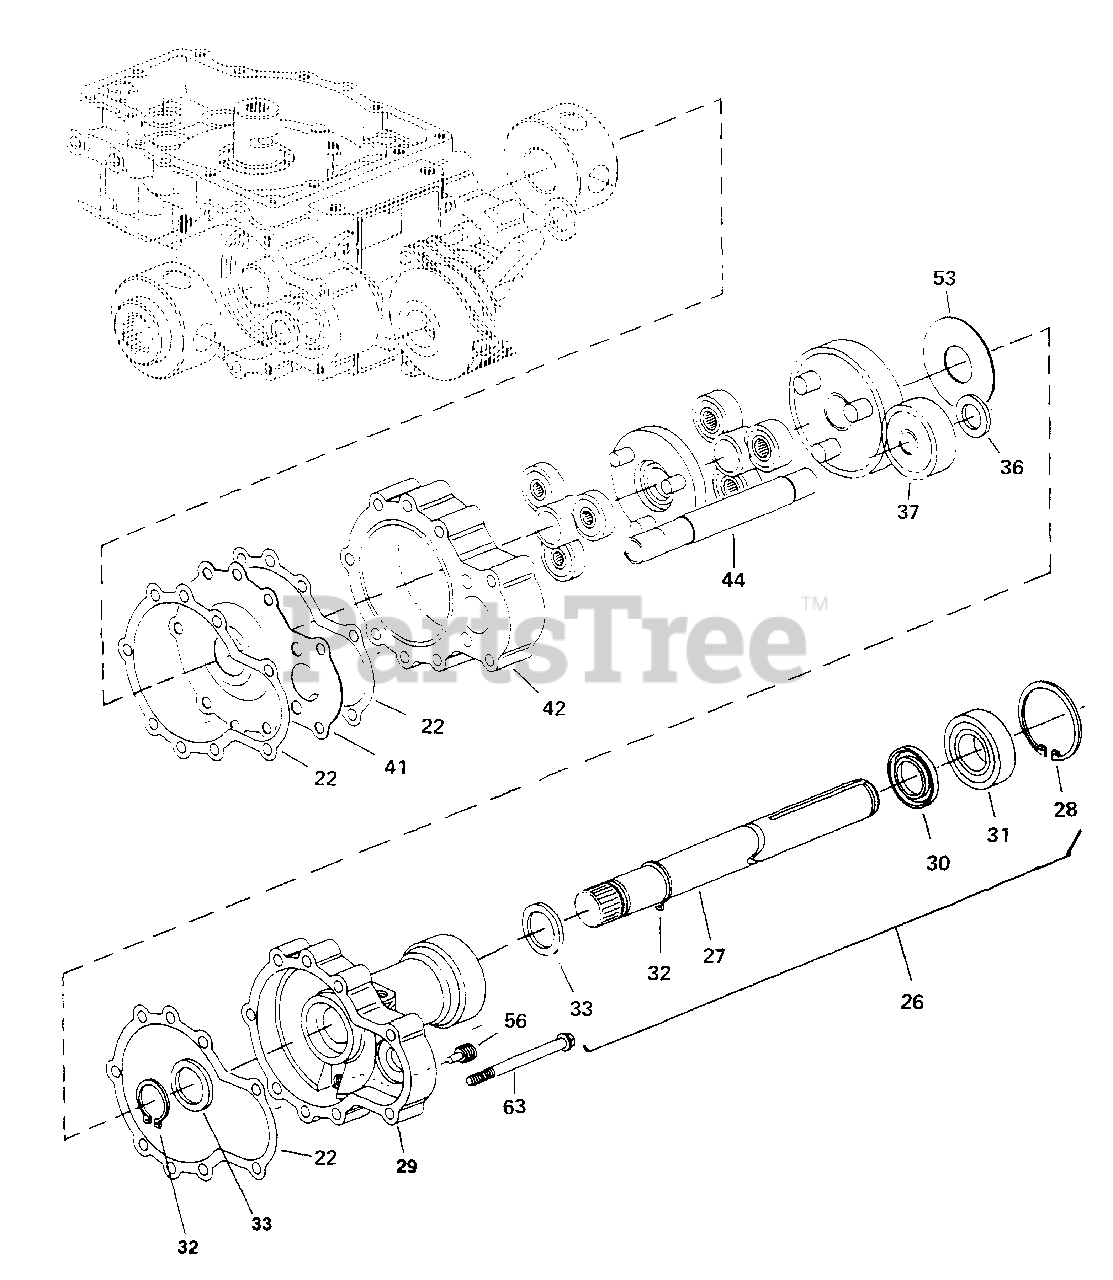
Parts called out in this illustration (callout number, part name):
22	GASKET, Axle Housing
26	AXLE HOUSING, S/A-B
27	SHAFT, Axle
28	RETAINING RING, Internal
29	HOUSING, Axle-B
30	LIP SEAL, Radial
31	BEARING, Ball
32	RING, Retainer
33	WASHER, Thrust
37	LOCK GEAR, Differential
41	PLATE, Wear
42	RING GEAR, A & B S/A, 57T
44	BRAKE SHAFT-B
53	WASHER, Thrust
56	PLUG, Magnetic
63	CAPSCREW, 1/4-20 Hex Flange x 2-3/4
63	GASKET OVERHAUL KIT (Incl. Ref. Nos. 19, 22 & 24)
